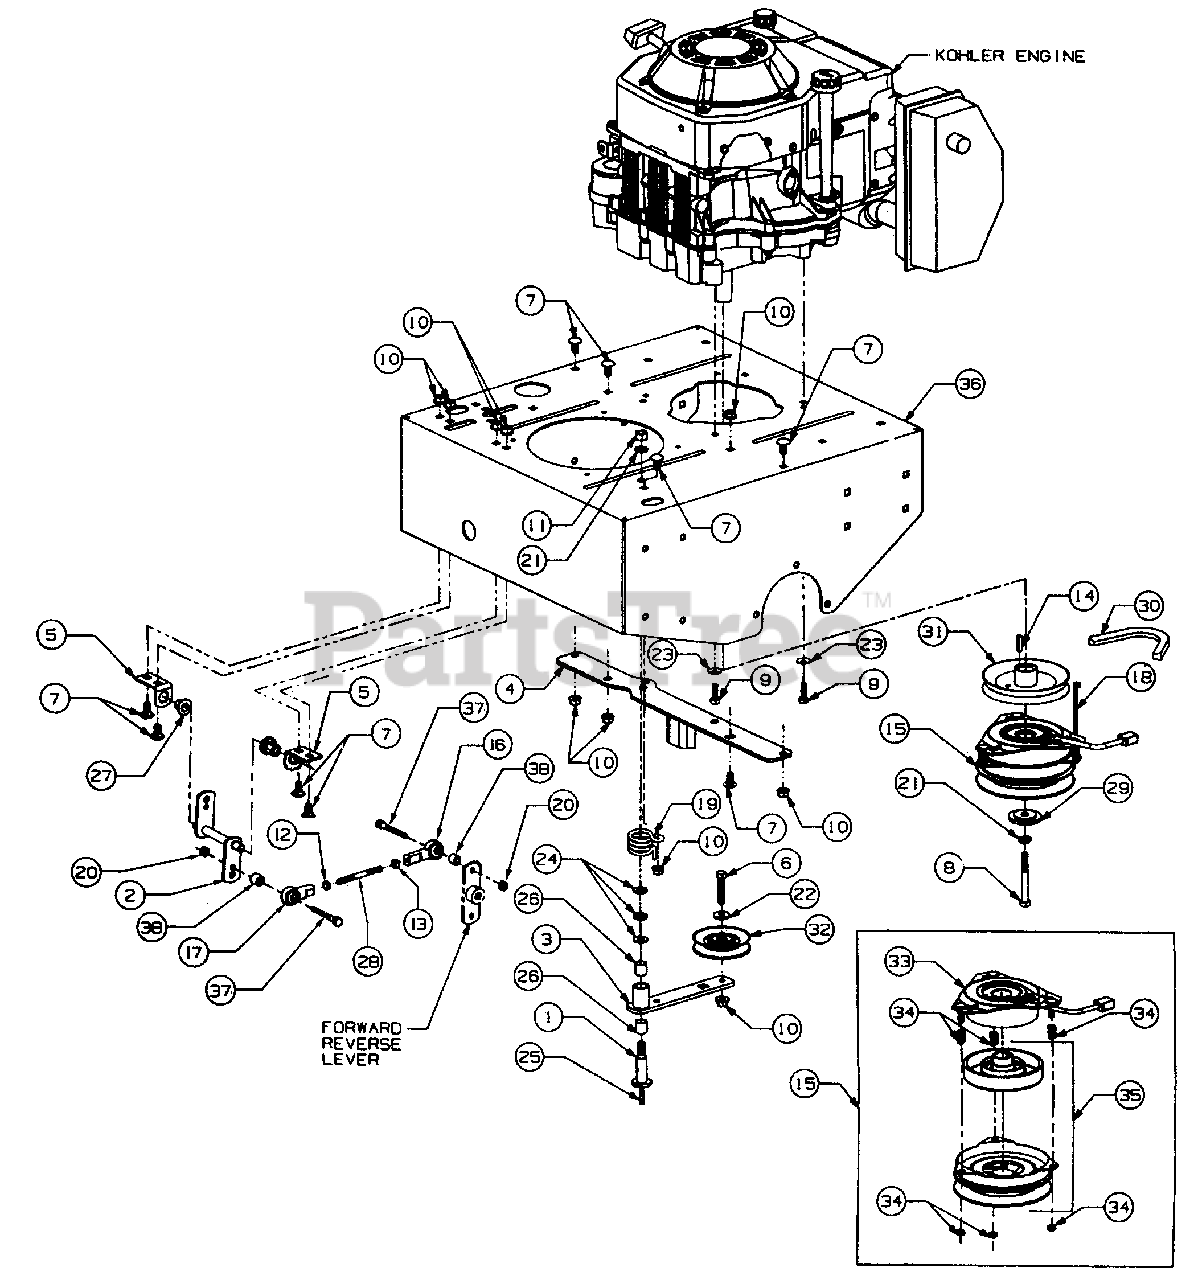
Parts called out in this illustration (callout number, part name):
1	Bolt, Shoulder
2	Lever, F/R Control
3	Arm Assy, Idler
4	Retainer, PTO Clutch
5	Bracket, Lever Angle
6	Screw, Hex Cap, 3/8-16 X 1.75 Lg
7	Bolt, Sht Nk Carriage, 3/8-16 X .75 Lg GR5
8	Screw, Hex Cap, 7/16-20 X 3.0 Lg GR5
9	Screw, Hex Cap M8 X 1.25 X 25 mm Lg
10	Nut, Hex Flanged Lock, 3/8-16
11	Nut, Hex, 7/16-14 GR5
12	Nut, Hex Jam, 5/16-24 LH Thread
13	Nut, Hex, 5/16-24 GR5
14	Key, Square, 1/4 X 1.0 Lg
15	Clutch Assy, PTO
16	Rod End, Spherical 5/16-24
17	Rod End, Spherical 5/16-24 LH Thread
18	Cable, Tie
19	Spring, Torsion
20	Nut, Hex Flange Lock, 5/16-18 GR 5
21	Washer, Lock, 7/16
22	Washer, Special .378 X 1.00 X .125 Thk
23	Washer, Bell, .340 X.872 X .060 Thk
24	Washer, Flat, .469 X .875 X .105 Thk
25	Fitting, Lube
26	Bearing, Sleeve
27	Bearing, Hex Flange
28	Rod, Control
29	Spacer, Clutch
30	Belt, Transmission 1/2 X 40.0 Lg
31	Pulley, Engine
32	Pulley, V-Idler
33	Field Assy
34	Mounting Accessories
35	Kit, Armature and Rotor
36	Deck w/Graphic, Engine Mtg
37	Screw, Hex Cap, 5/16-18 X 1.38 GR 5
38	Spacer .317 ID X .625 OD X .343 Lg
